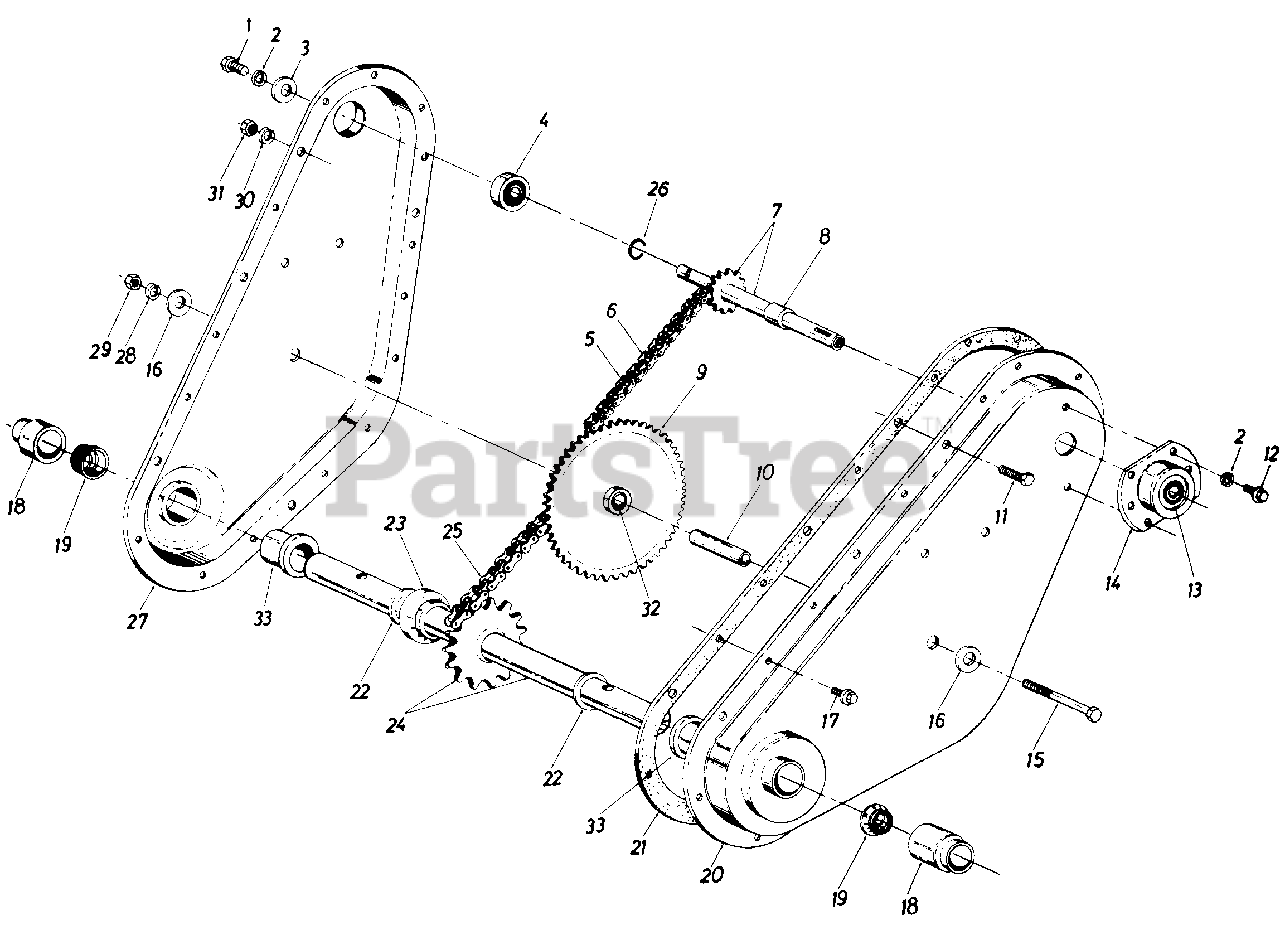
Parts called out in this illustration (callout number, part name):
1	Hex L-Scr. 1/4-28 x .625" Lg.
2	L-Wash. 1/4" Scr.
3	Fl-Wash. .25" I.D. x .93" O.D. x .125" Thk.
4	Bearing .62" I.D. x 1.38" O.D. x .437" Thk.
5	#35 Chain 3/8" Pitch x 52 Links-Endless
6	Master Link
7	Input Shaft Assembly
8	Spacer
9	Sprocket Assembly
10	Sprocket Hub Tubing 3/8" I.D. x 5/8" O.D. x 1.9" Lg.
11	Hex Scr. 5/16-18 x .625" Lg.
12	Hex Wash. Hd. Self-Tap Scr.1/4-20 x .50" Lg.
13	Bearing .625" I.D. x 1.38" O.D. x .437" Thk.
14	Bearing Housing
15	Hex Scr. 3/8-24 x 2.75" Lg.
16	Fl-Wash. 3/8" I.D. x 1.25" O.D. x .100 Thk.
17	Hex Wash. Hd. Self-Tap Scr.1/4-20 x .50" Lg.
18	Dust Cap
22	Thrust Wash. 1.00" I.D. x .030" Thk.
23	Step Spacer
24	Tine Shaft Assembly
25	#50 Chain 5/8" Pitch x 46 Links-Endless
26	Snap Ring 518" Dia. Shaft
29	Hex Nut 3/8-24 Thd.
30	L-Wash. 5/16" Scr.
31	Hex Nut 5/16-18 Thd.
32	Bearing
33	Bearing
